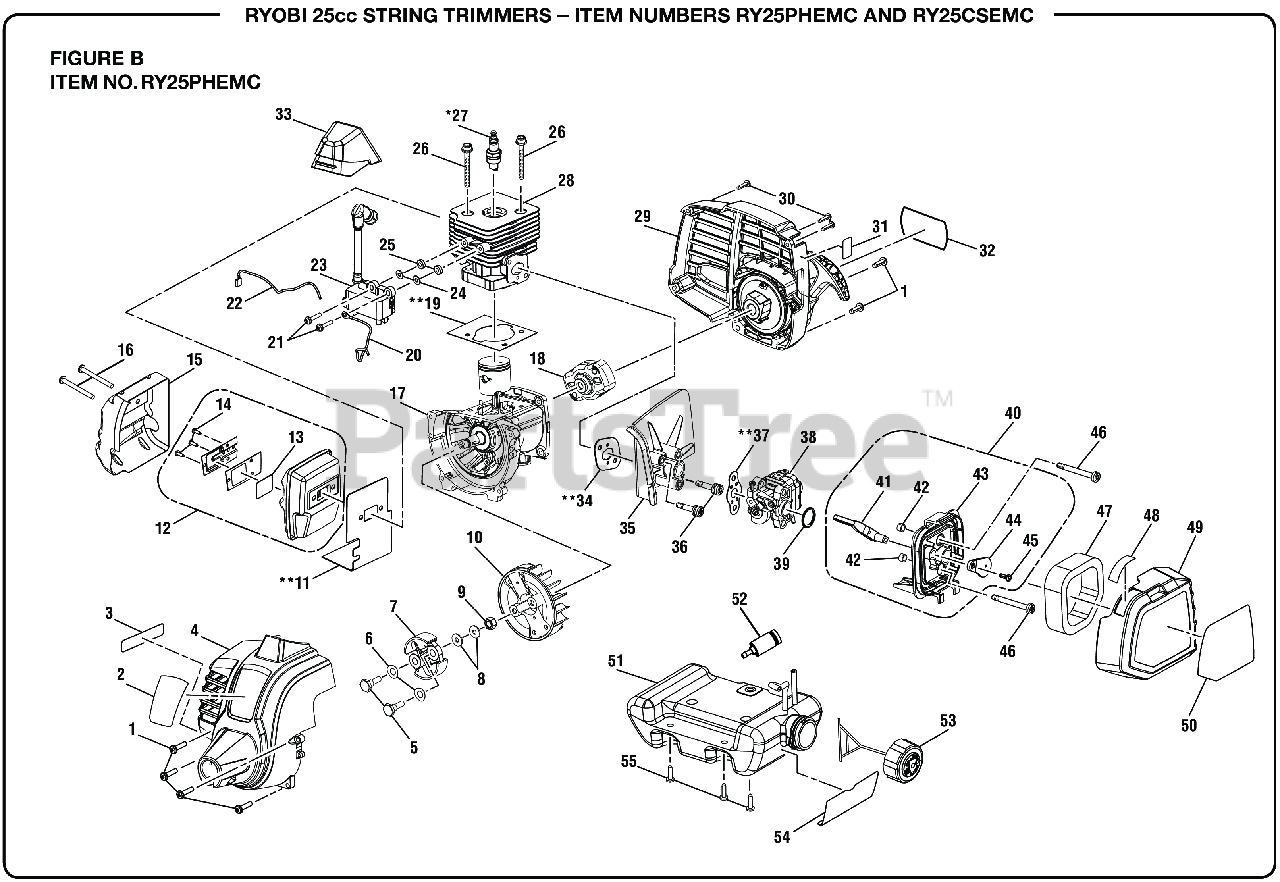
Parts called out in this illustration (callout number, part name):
1	Cap Screw w/Washer (M5 x 16 mm, T25 Torx Soc. Hd.)
2	Logo Label (Front)
3	Warning Label (Combustion)
4	Front Housing Assembly
5	Clutch Shoulder Bolt (M6 x 22.5 mm, Hex Hd.)
6	Washer (Curved)
7	Clutch Assembly
8	Washer (ID6 x OD15 x 1.2t)
9	Flange Nut (M8, Flywheel)
11	Muffler Gasket
12	Muffler Assembly
13	SCREEN
14	Screw (6-20 x 1/4 in., T20 Torx Pan Hd. S.T.)
15	HEAT SHIELD
16	Screw (M5 x 50 mm, Torx Slotted Recessed Pan Hd.)
17	Crankcase Assembly
18	Starter Cup
19	Gasket
20	Lead Wire Assembly, Red
21	Screw (M4 x 22 mm, T20 Torx Slotted Recessed Pan Hd.)
22	Lead Wire Assembly, Black
23	Coil Boot Assembly
24	Flat Washer (OD10 x ID42 x 1t)
25	Phenolic Spacer (Ignition Module)
26	Screw (M5 x 22 mm, T25 Torx Soc. Hd.)
27	SPARK PLUG CHAMPION - RCJ-6Y
29	Rear Housing and Starter Assembly
30	Screw (M4 x 20 mm, T20 Torx Pan Hd. S.T.)
31	Primer Bulb Location Label
32	Shoulder Screw (M4 x 14 mm, T25 Torx Truss Hd.
33	Spark Plug Boot
34	Heat Dam Insulator
35	Screw (M5 x 30 mm, T25 Torx Pan Hd. S.T.)
36	Screw w/Washers (M5 x 30 mm, T25 Torx Pan Hd.)
37	Gasket
38	Carburetor Assembly
39	Carburetor O-Ring
40	Airbox Base Assembly
41	Compression Limiters
42	Washer (ID5.8 x OD11.5 x 1.7t)
43	Air Box Base
44	Screw (M4 x 12 mm, T20 Torx Pan Hd. S.T.)
45	Screw (M4 x 12 mm, Slotted Recessed Pan Hd.)
46	Screw (M5 x 44 mm,T25 Torx Hd. Carburetor)
47	Air Filter (Element)
48	Choke Position Label
49	Airbox Cover (Inc. Key Nos. 48 & 50)
50	Starting Instructions Label
51	Fuel Tank and Cap Assembly
52	Fuel Filter
53	Fuel Cap Assembly
54	Fuel Mixture Label
55	Shoulder Screw w/Washer (M4 x 14 mm, T25 Torx Truss Hd.)
